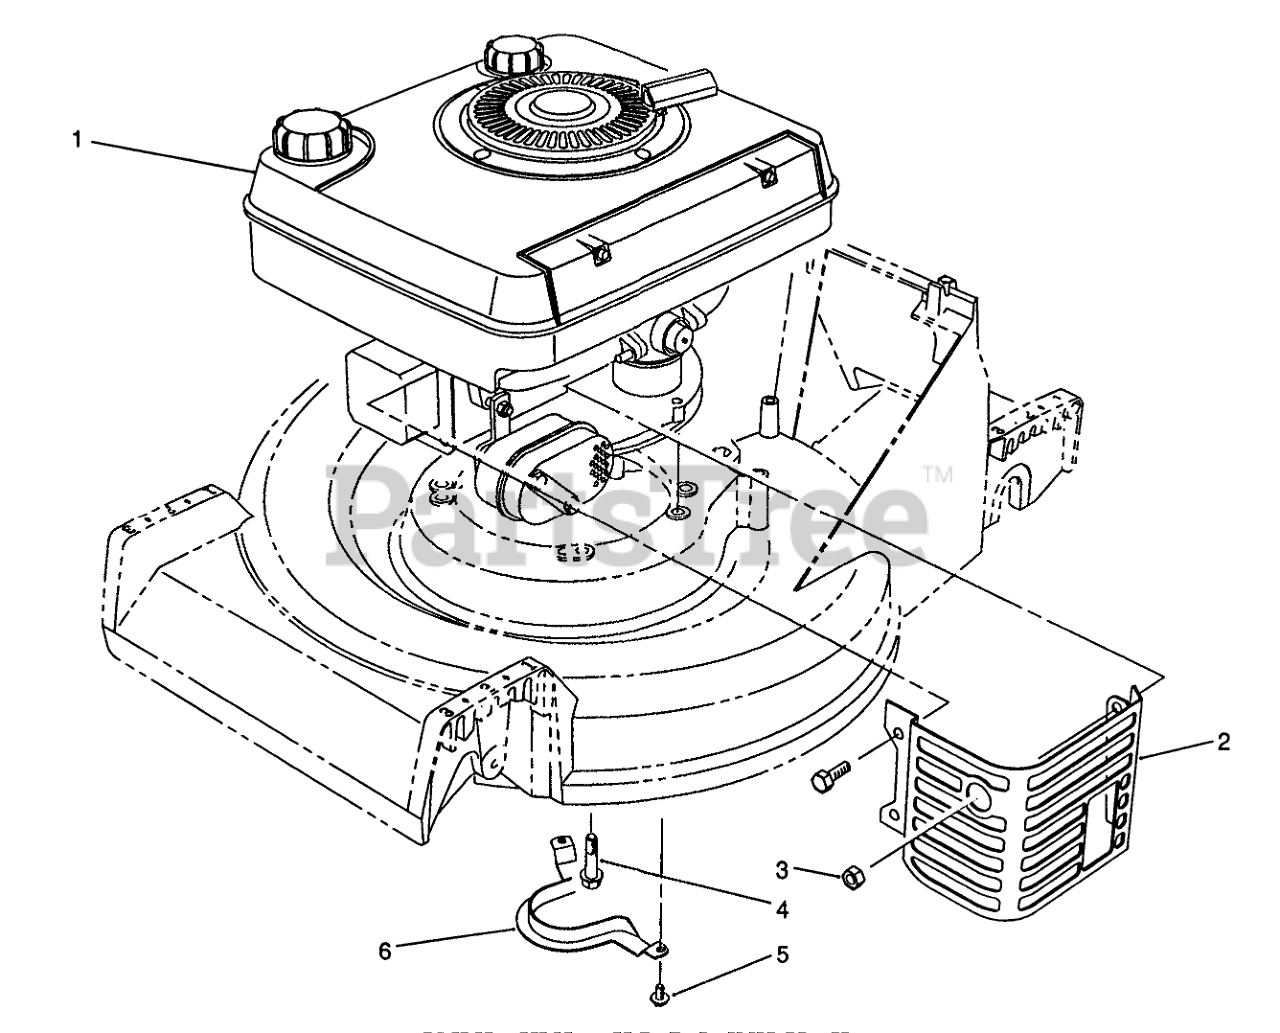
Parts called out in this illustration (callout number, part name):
2	Heat Shield-Muffler
3	NUT - LOK,KEPS 1/4-28NF
4	SCREW-HWHTF
5	SCREW-HWHTF
6	Guide-Belt
